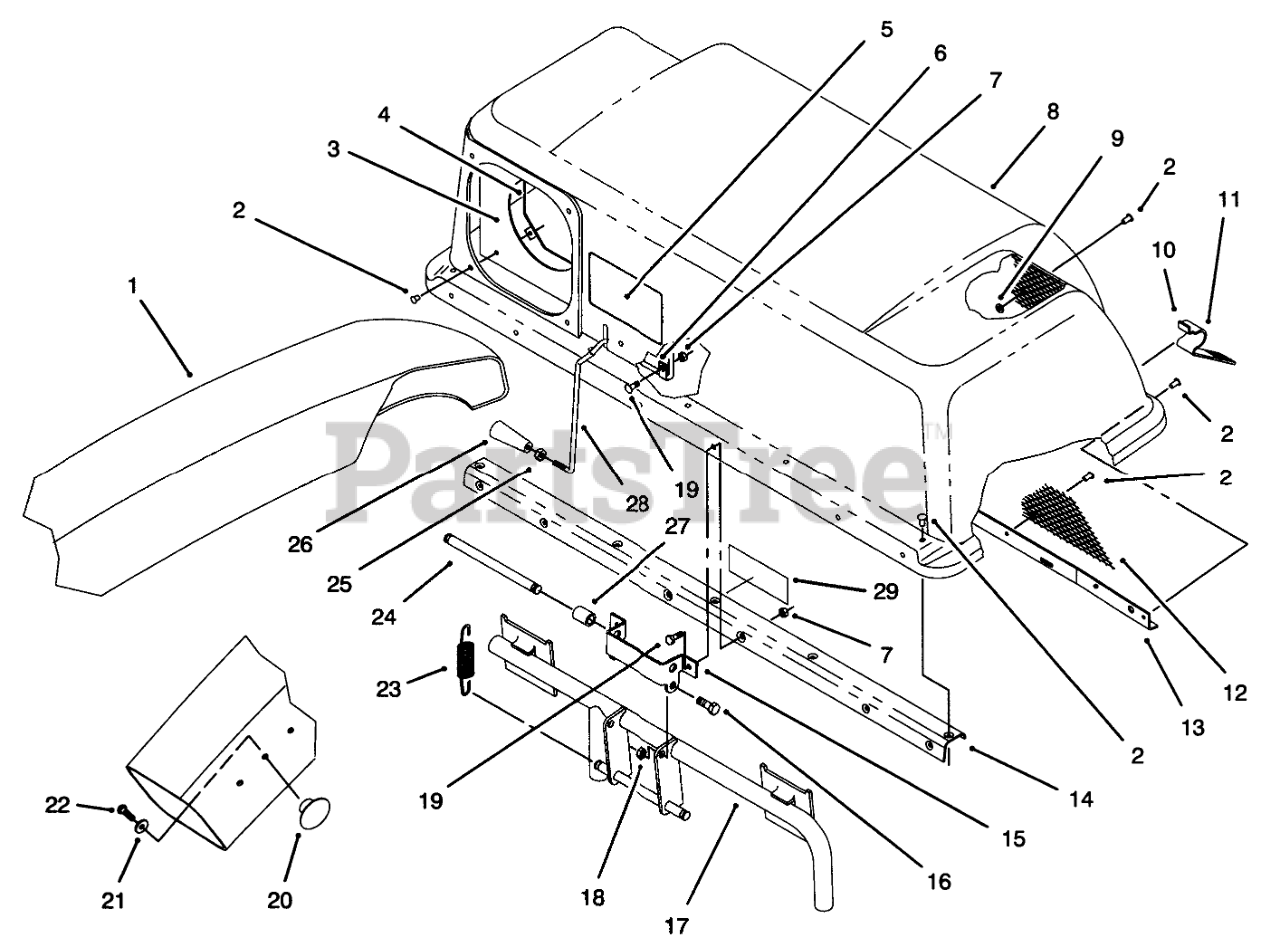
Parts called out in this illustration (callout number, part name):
1	CHUTE-DISCHARGE
2	RIVET-BLIND
3	SEAL-CHUTE
4	CLAMP-SEAL
5	DECAL
6	CLAMP
7	NUT-LOCK, NI
8	TOP-BAGGER
9	WASHER-FLAT
10	Latch-Bag
12	SCREEN-BAGGER
13	Screen Support
14	Stiffener-Bagger (Incl. Ref. #29)
15	HINGE-BAG TOPB
16	SCREW-HH
17	FRAME ASM
18	NUT-LOCK, NI
19	SCREW-HH
21	WASHER-PLAIN
22	SCREW-PPHTF
23	SPRING-EXTENSION
24	PIN-SPRING
25	NUT-JAM
26	HANDLE-TAPERED
27	Spacer
28	FEELER-FILL, BAG
29	DECAL-CAUTION
